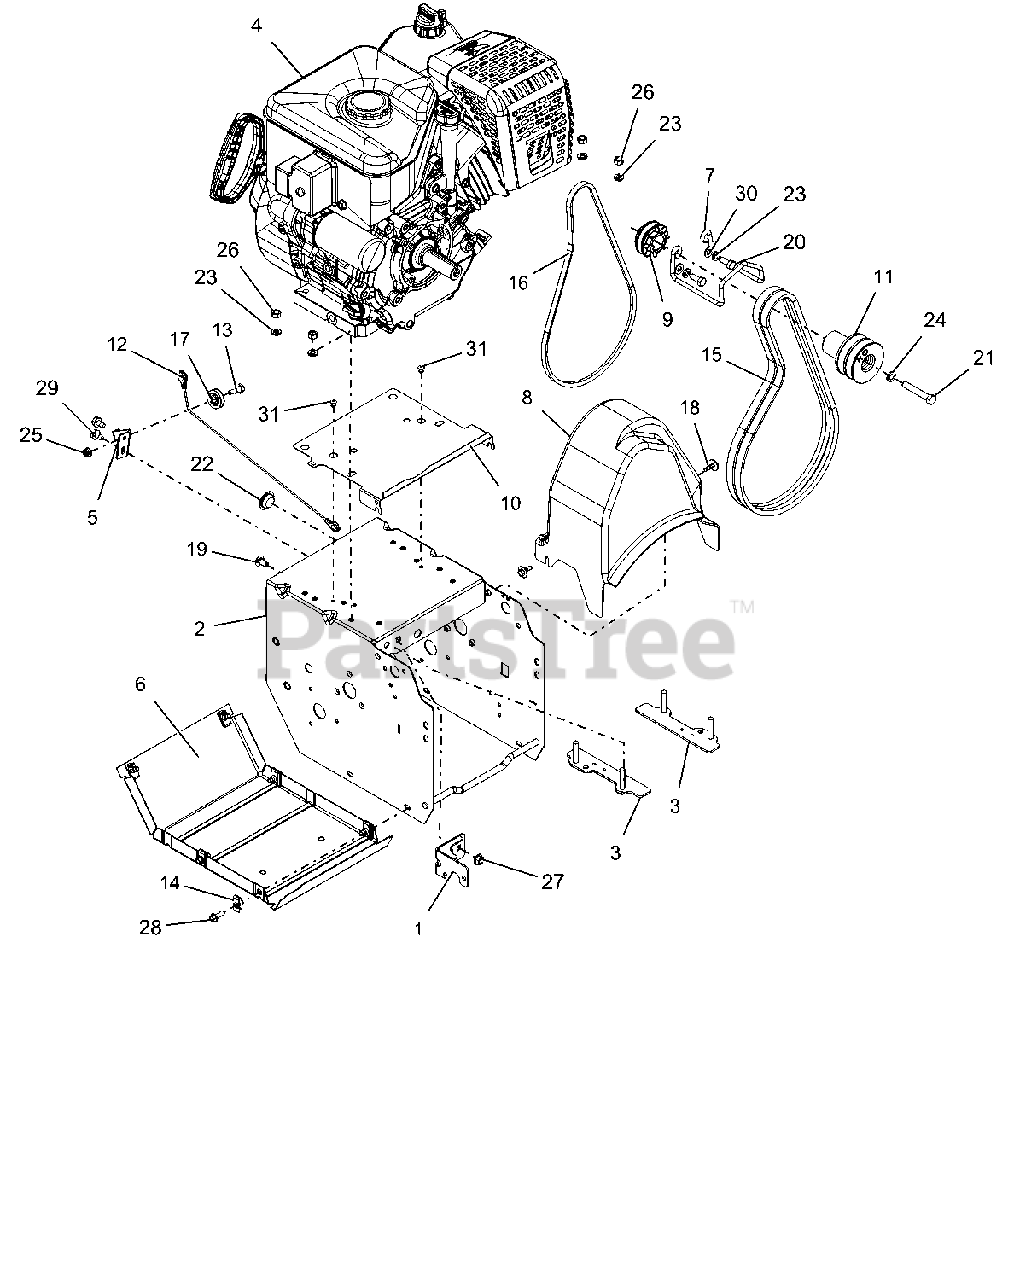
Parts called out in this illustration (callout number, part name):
1	WELDMENT, FRAME BRACKET
2	WELDMENT, FRAME - DELUXE 16"
3	STRAP,ENGINE BOLT,ARIENS LRG
4	ENGINE, AX414 GEN 3 120V/60W
5	BRACKET, CABLE PULLEY
6	COVER, BOTTOM
7	FINGER, BELT
8	BELT COVER
9	SHEAVE, DRIVE
10	BAFFLE,ENGINE,ARIENS LRG BLOCK
11	SHEAVE,ATTACHMENT 2-GRV
12	CABLE, LOWER TRACTION (DELUXE)
13	BOLT, SHLDR-.375X.375X.25-20
14	NUT-RTNR .25-20X.56
15	V-BELT, HA-RAW EDGE (SET)
16	V-BELT, 3L-RAW EDGE
17	PULLEY, CABLE
18	SCR-TAP .25-20X.5 CAPTIVE
19	@BLT-RHDSSQNK .31-18X.62 G5YZ
20	BLT-HEX .31-24X.75 YWZC GR5
21	BLT-HEX .38-24X2.25 YWZC GR5
22	PLUG, HOLE - .875" NYLON
23	WSHR-LK .312X.097 HVY YWZC
24	@WSHR-LK .38X.094 REG YWZC
25	@NUT-LK-CTR-FLG .25-20 YWZC
26	@NUT-HEX .31-18 YWZC
27	@NUT-LK-TOP-FLG .31-18 YWZC
28	BLT-HEX .25-20X.75 HWH YZ GR5
29	@SCR-TAP .31-18X.50 HWH TR YWZ
30	@WSHR-FL-STL.344X.688X.065YWZC
31	RVT-POP .187 YZ
